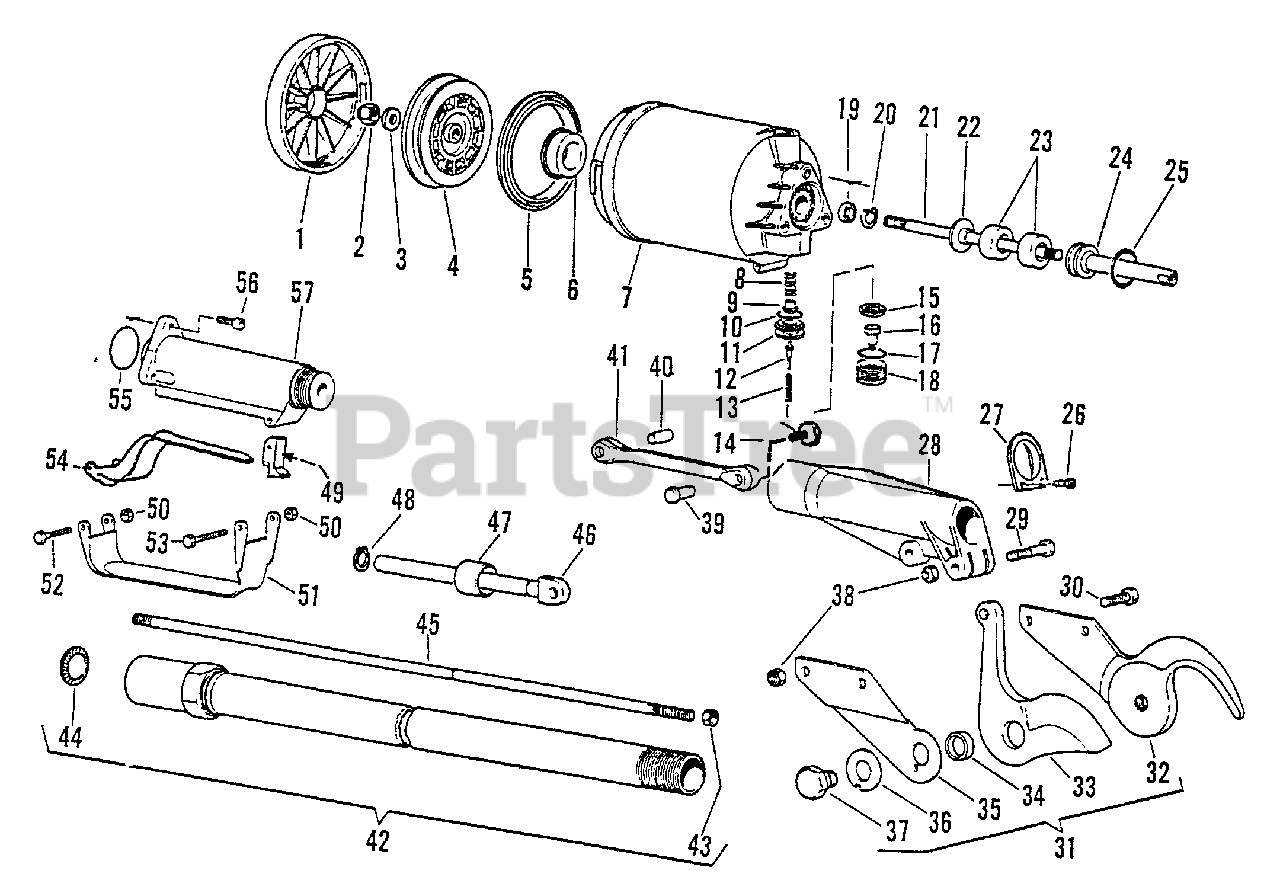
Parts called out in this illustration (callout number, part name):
1	COVER, PISTON
2	LOCKNUT
3	WASHER
4	PISTON
5	RING, PISTON
6	STOPPER
7	BODY, CYLINDER
8	SPRING
9	SEAL
10	O-RING
11	HOLDER, SEAL
12	VALVE
14	BOLT, RETAINING
15	SEAL
16	VALVE, PISTON
17	O-RING
18	END, VALVE
19	GASKET
20	CLIP, SPRING
21	ROD TO AIR PISTON
22	PLATE
23	STOPPER
24	ROD, PISTON
25	O-RING
26	SCREW
27	SHIELD, DUST
28	SUPPORT, HOUSING
29	BOLT
30	BOLT
31	COMPLETE BLADE - TYPE B
32	ANVIL - TYPE B
33	BLADE - 40" (101cm) -- LOWER
34	SPACER
35	SUPPORT, BLADE
36	WASHER, SPECIAL LOCK
37	BOLT, BLADE
38	LOCKNUT
39	PIN, END
40	PIN, CONNECTING
41	ROD
42	EXTENSION, 2 METER
43	NUT
44	WASHER
45	ORDER ITEM 42
46	ROD
47	GUIDE, NYLON PISTON
48	CLIP, SPRING
49	SAFETY
50	LOCKNUT
51	GUARD, HANDLE
52	PIN, HANDLE
53	PIN, HANDLE
54	TRIGGER
55	O-RING
56	BOLT
57	BODY, CYLINDER
